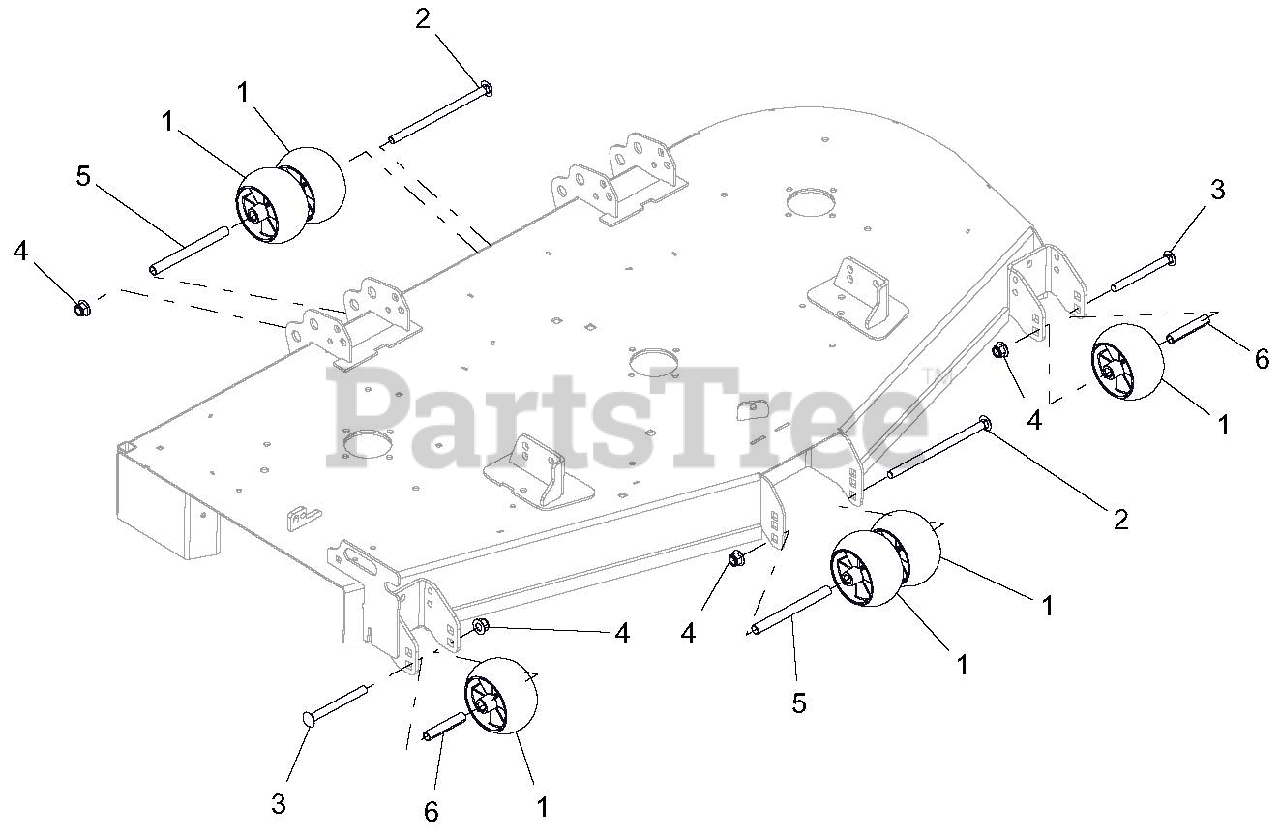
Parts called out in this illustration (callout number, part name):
1	ANTI-SCALP WHEEL - 5X3 CTR
2	BLT-RDHDSQNK .50-13X8.50 Y
3	BLT-RDHDSQNK .50-13X5.00 G5 YWZC
4	NUT-LK-NYL-FLG .50-13 YWZC
5	SPACER, .510 X .625 X 6.50
6	SPACER, .510X.625X3.35
